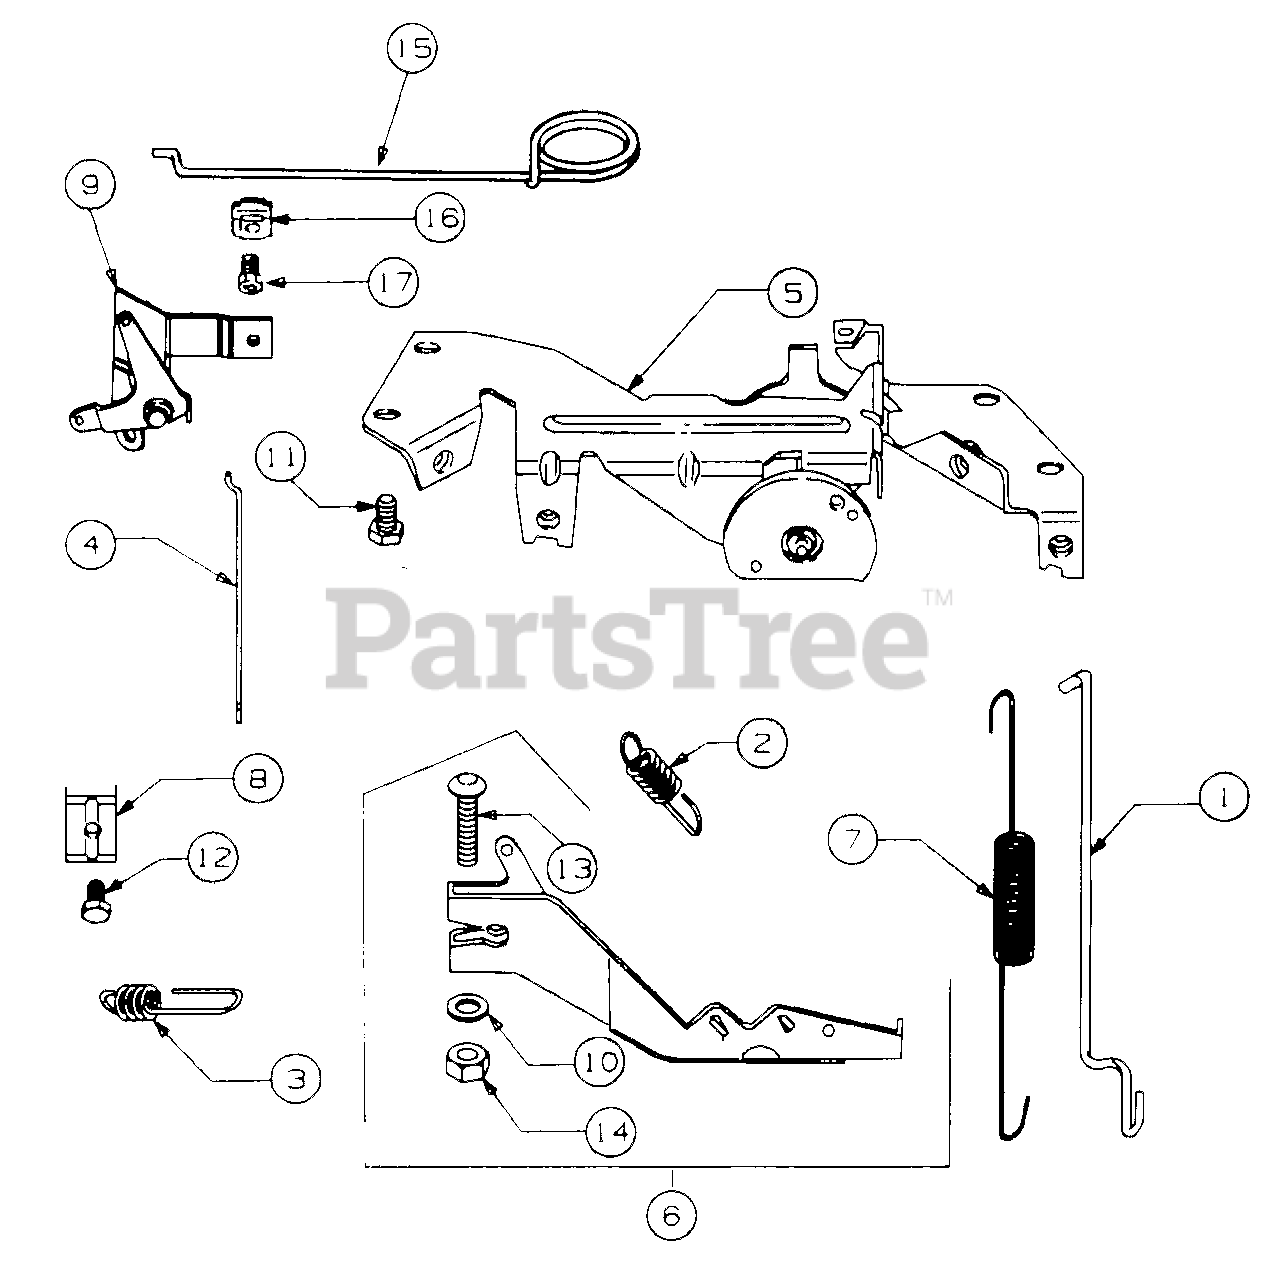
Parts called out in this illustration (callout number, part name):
1	Link, Governor
2	Spring, Governor
3	Spring, Governed Idle
4	Link, Choke
5	Bracket, Governor Control
6	Lever Assy, Governor
7	Spring, Governor Link
8	Clamp, Casing
9	Bracket, Choke Control
11	Screw, Sem
12	Screw, Hex Head
14	Nut, Hex
15	Rod, Manual Choke
16	Clip, Frictbn
17	Screw, Sem
